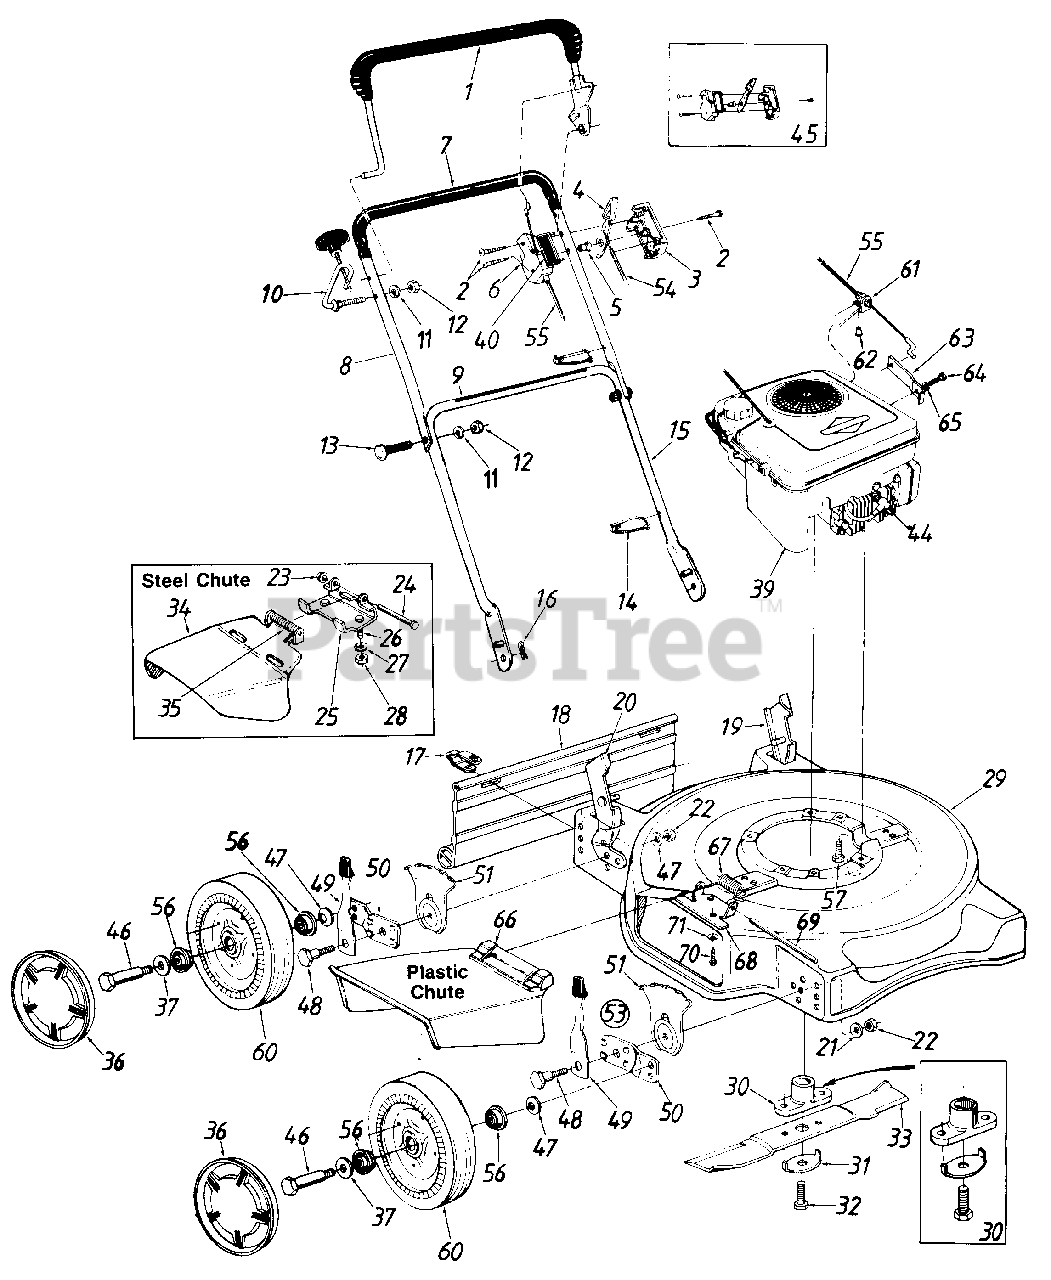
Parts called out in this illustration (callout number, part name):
2	SCREW-TRUSS MACH
3	PANEL HALF-CONTROL
4	LEVER-THROTTLE CONT-REV
5	PIN-CONTROL DISC
6	PANEL HALF-CLUTCH
7	GRIP-SHRINK-25 IN
8	HANDLE-UPPER
10	SCREW-RECOIL HANDLE GUIDE
11	WASHER-LOCK-5/16
12	NUT-HEX 5/16-18
13	BOLT-CARRIAGE-CURV 5/16-18 x 1.38
14	TIE-CABLE
15	LOWER HANDLE
16	PIN-INTERN COT-5/16 DIA
17	CLIP-HINGE
18	FLAP-RR
19	BRACKET ASSY-HDLE-LH
20	BRACKET ASSY-HDLE-RH
21	WASHER-BELL .390 ID x 1.375 x .062
22	NUT-HEX 3/8-16
23	NUT-PUSH
24	PIN-PIVOT
25	PLATE-ADAPTER
26	LOCK WASHER 1/4 DIA
27	LOCK WASHER 1/4 DIA
28	NUT-HEX 1/4-20
31	KIT-BLADE MOUNTING
32	SCREW-HEX 7/16-20 x 1.50
33	BLADE-19.88IN
34	DEFLECTOR ASSY-CHUTE
35	SPRING-TORSION
36	HUB CAP
37	WASHER-FL-.531 x .930 OD x .050
44	INSULATOR-SPARK PLUG
45	KIT-THROTTLE CONTROL
46	SCREW-SHLD .498 DIA x 1.450
47	WASHER-BELL .400 ID x .88 x .060
48	SCREW-SHLD
49	LEVER & KNOB ASSY
51	PLATE-HGT ADJ
53	ADJUSTER ASSY-HGT-RH
54	WIRE-THROTTLE
55	CABLE-CONTROL
56	BEARING-BALL
60	WHEEL ASSY W/TIRE
61	BRACKET-CABLE MTG
63	BRACKET-MTG
64	SCREW-TRUSS MACH #10-24 x .50
65	WASHER-LOCK-#10
66	DEFLECTOR ASSY-CHUTE
67	SPRING-TORSION
68	PLATE-ADAPTER
69	PIN-HINGE
70	SCREW-HEX WASH SF TAPP
71	WASHER-SPRING BELL
17036-0483	DECK ASSEMBLY-20INCHARCOAL - CHARCOAL GRAY (0483)
17036-0498	DECK ASSEMBLY-20IN(CUB YELLOW) - OLD CUB YELLOW (0498)
17036-0629	DECK ASSEMBLY-20INSILVER FLAK - SILVER FLAKE (0629)
17036-0638	DECK ASSEMBLY-20IN - MTD/TROY-BILT RED (0638)
17036-0662	DECK ASSEMBLY-20IN(OYSTER GRAY) - OYSTER GRAY (0662)
